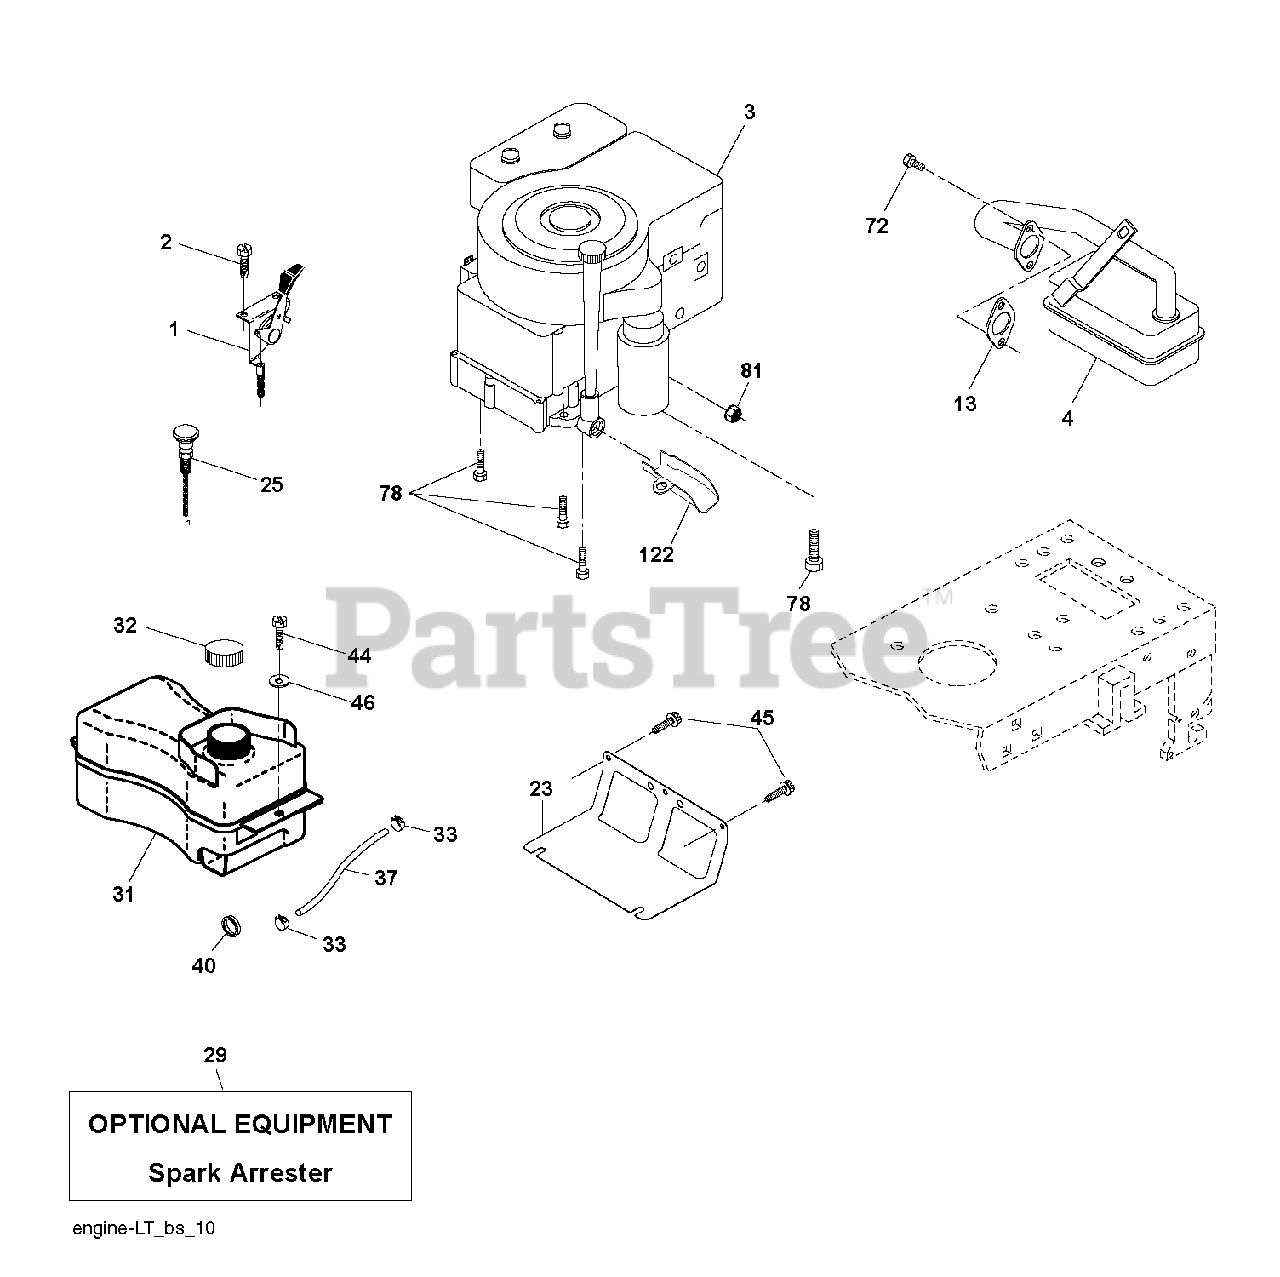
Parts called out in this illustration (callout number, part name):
1	CONTROL TH/CH FLAG
2	SCREW
13	REPL BY 532 27 22-93
23	SHEILD.BROWNING.DBR.GUARD
25	KNOB.ERGO.EXTENDED.RED (1 2)
29	ARRESTER SPARK (OPTIONAL)
32	CAP ASM.FUEL.2.25"FR.
44	SCREW HEXWSHR 1/4-20X3/4
45	SCREW, 3/8-16X3/4
72	SCREW.SOCKET HD.5/16-1
81	NUT
122	EXTENSION DRAIN OIL
